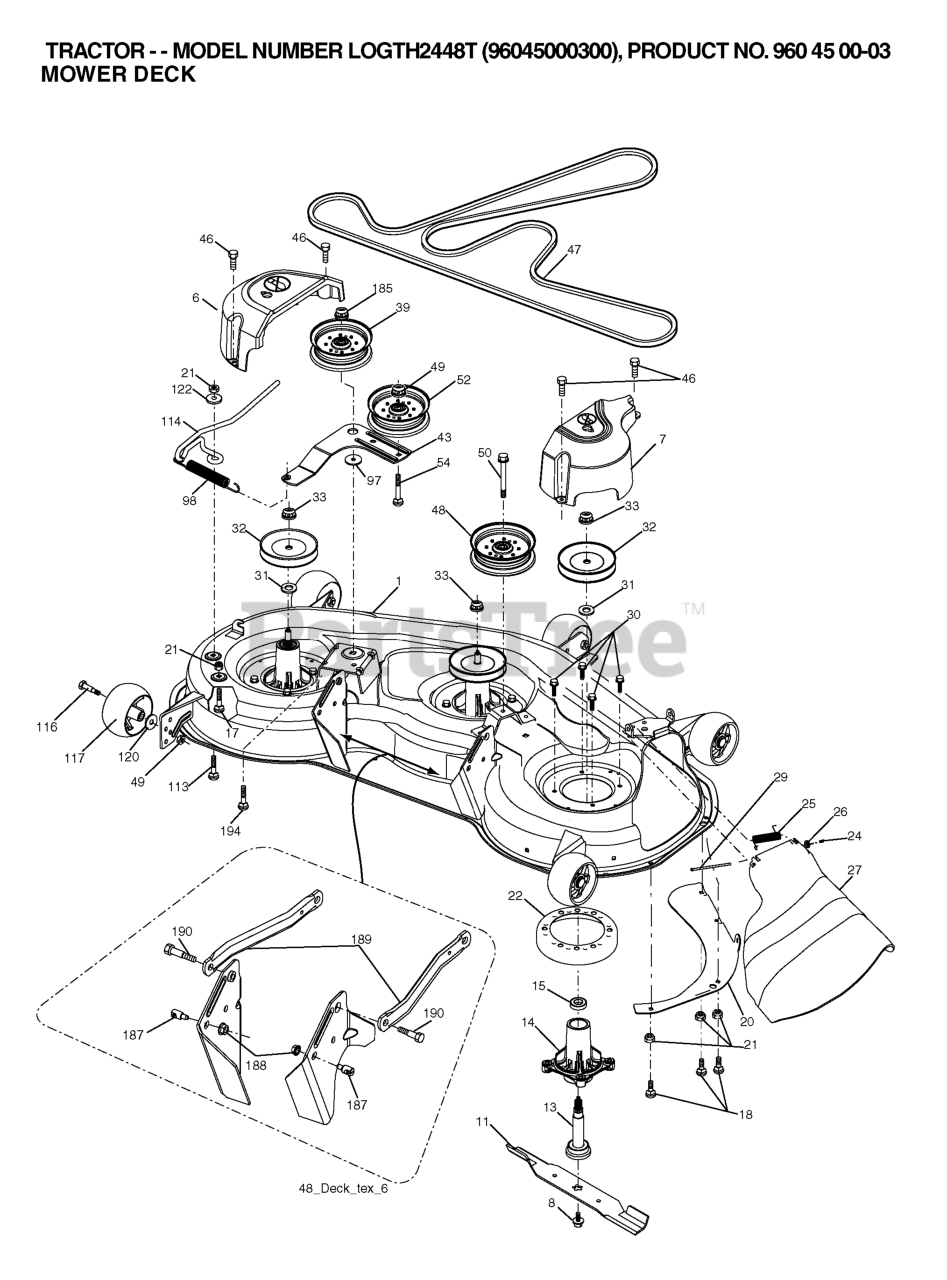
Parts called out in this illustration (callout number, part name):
1	THROTTLE CONTROL
2	SCREW
4	MUFFLER.TWIN.CYL.LOW.TONE
5	RP.PIPE-EXHAUST LH
6	RP.PIPE-EXHAUST RH
8	BOLT.5/16-18UNCX3/4 W/SEMS.BLK
10	RP SHIELD HEAT MUFFLER
13	GASKET.EXHAUST.KOHL.CV18-CV26
14	TUBE, DRAIN OIL ASM.
17	SCREW 3/8-16X1
23	SHIELD.BROWNING.DBR.GUARD
25	CONTROL, CHOKE
29	KIT.SPARK ARRESTOR 794945 B&S
31	TANK.ASM.FUEL.FR.2.5GA.
32	FUEL CAP
33	HOSE CLAMP
37	LINE.FUEL.20
38	PLUG DRAIN OIL EASY
44	SCREW HEXWSHR 1/4-20X3/4
45	SCREW, 3/8-16X3/4
72	SCREW.SOCKET HD.5/16-1
81	NUT
119	LENKRAD
120	GUARD 532199767
122	SCREW.1/4-20X5/8
123	SCREW, 5/16-18 X 1/2
